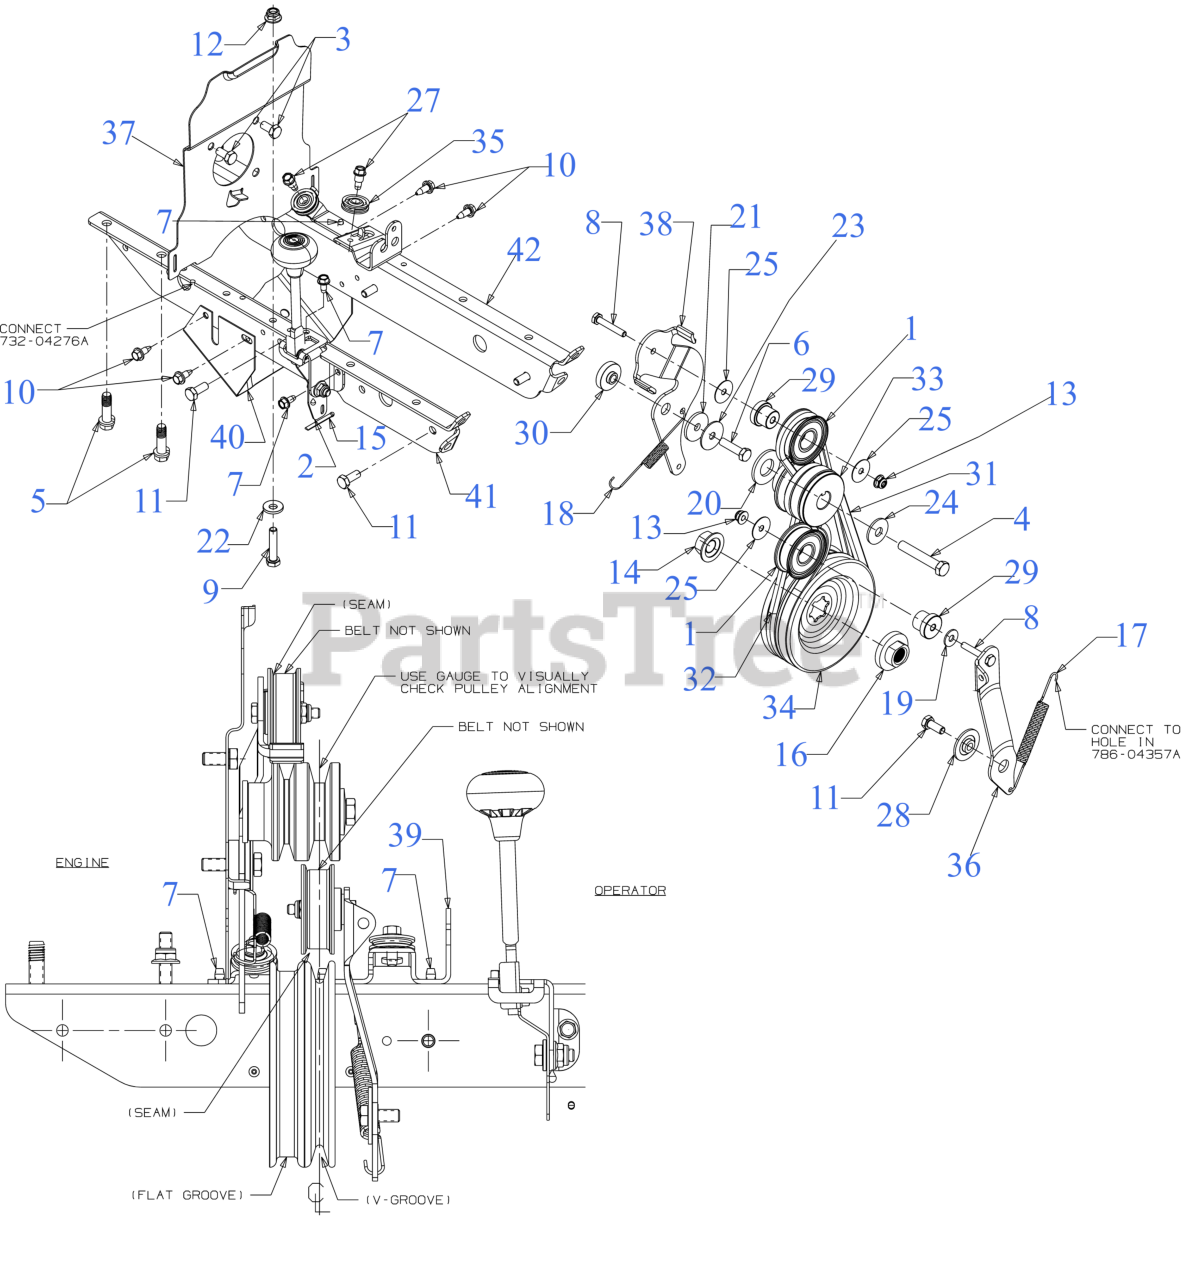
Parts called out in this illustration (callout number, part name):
1	IDLER PULLEY ASSEMBLY
2	Not Serviceable/ Components Only
3	HEX SCREW 5/16-24 x .62
4	HEX SCREW 3/8-24 x 2.25 GR5
5	SCREW 3/8-16 x 1.250
6	SCREW 5/16-24 x 1.25 GR5
7	SCREW 1/4-20 X.500
8	SCREW 1/4-20 x 1.50 GR.5
9	SCREW 5/16-18 x 1.5 LG
10	SCREW 1/4-14 x .625
11	SCREW 5/16-18 x .750
12	FLANGE LOCK NUT 5/16-18
13	FLANGE LOCK NUT
14	FLANGE NUT W/HUB
15	COTTER PIN-5/32 DIA
16	PULLEY HUB
17	RETURN SPRING
18	EXTENSION SPRING
19	FLAT WASHER .28 ID x .74 OD x .063
20	FLAT WASHER
21	WASHER-5/16 x 1.25X 1.27
22	BELLVILLE WASHER .827 x .331 x .098
23	FLAT WASHER 0.315x1.255x0.060 HD
24	BELL WASHER
25	FLAT WASHER
27	SHOULDER SCREW
28	PIVOT IDLER SPACER
29	SHOULDER SPACER
30	PIVOT IDLER SPACER
31	V-BELT 4L x 25.375
32	V-BELT 3L x 29.125
33	ENGINE PULLEY
34	TRANSMISSION PULLEY
35	CABLE GUIDE ROLLER
36	FORWARD IDLER BRACKET
38	REVERSE IDLER BRACKET
